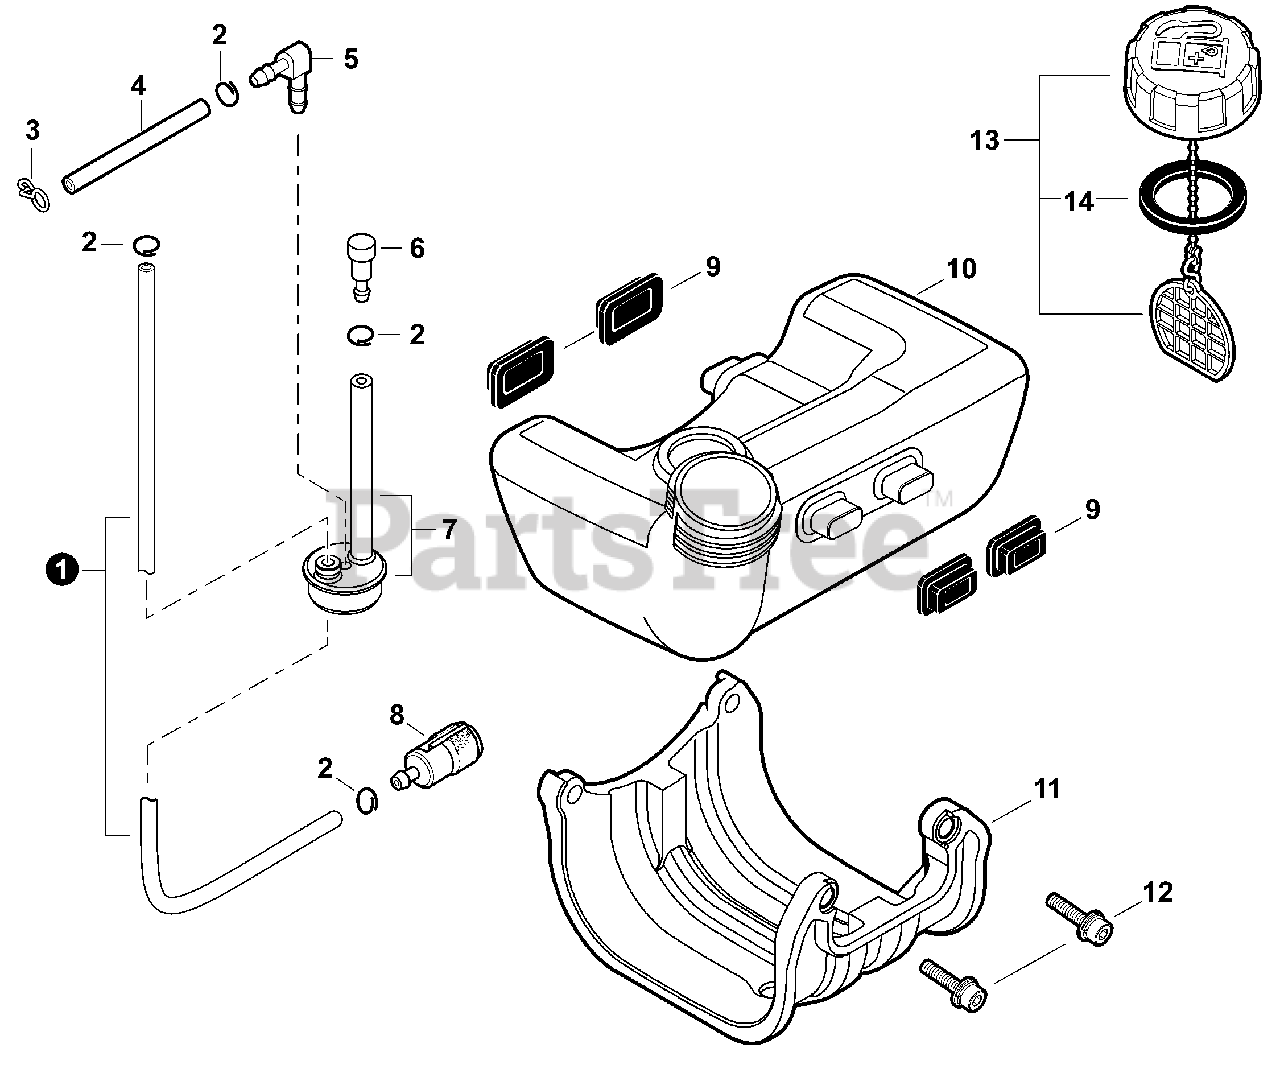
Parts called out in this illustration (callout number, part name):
1	PIPE, FUEL 3.3×6×160
2	CLIP Ø6
3	CLIP, SPRING Ø5.2
4	PIPE, FUEL RETURN L= 52.5 MM
5	CONNECTOR, PIPE
6	VENT ASSY
7	GROMMET, FUEL W/VENT PIPE
8	FILTER, FUEL
9	CUSHION, FUEL TANK
10	TANK, FUEL
11	GUARD, PLASTIC FUEL TANK
12	BOLT M5×20
13	CAP ASSY, FUEL
14	GASKET, FUEL CAP
